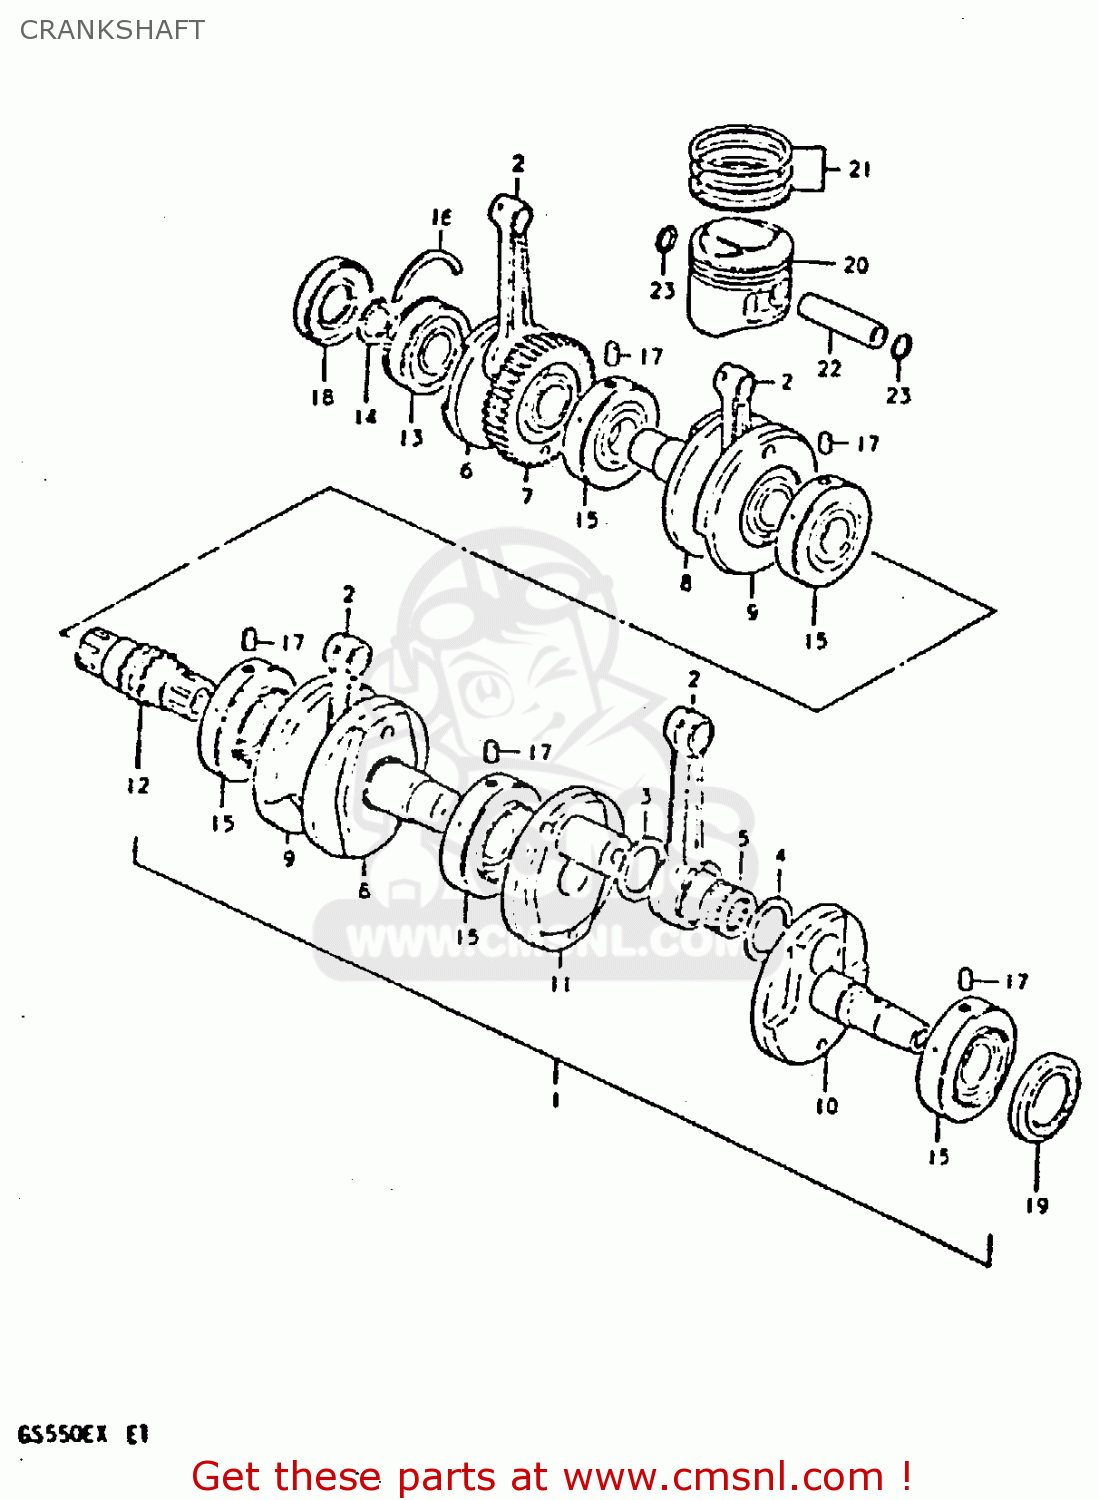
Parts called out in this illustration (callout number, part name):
1	CRANKSHAFT ASSEMBLY
2	ROD,CONNECTING
3	WASHER (28X48X2)
4	WASHER(28X48X1)
5	ROLLER BEARING (28X38X16.8)
6	CRANKSHAFT
7	WEB,CRANK
8	CRANKSHAFT
9	WEB,CRANK,MIDDLE
10	CRANKSHAFT,LEFT
11	WEB,CRANK,LEFT
12	SHAFT,TIMING CHAIN DRIVE
13	BEARING(30X72X19)
14	CIRCLIP,30MM
15	BEARING
16	C RING
17	PIN
18	SEAL,OIL(30X72X11)
19	OIL SEAL
20	PISTON
21	RING SET,PISTON
22	PIN,PISTON 16MM
23	CIRCLIP
